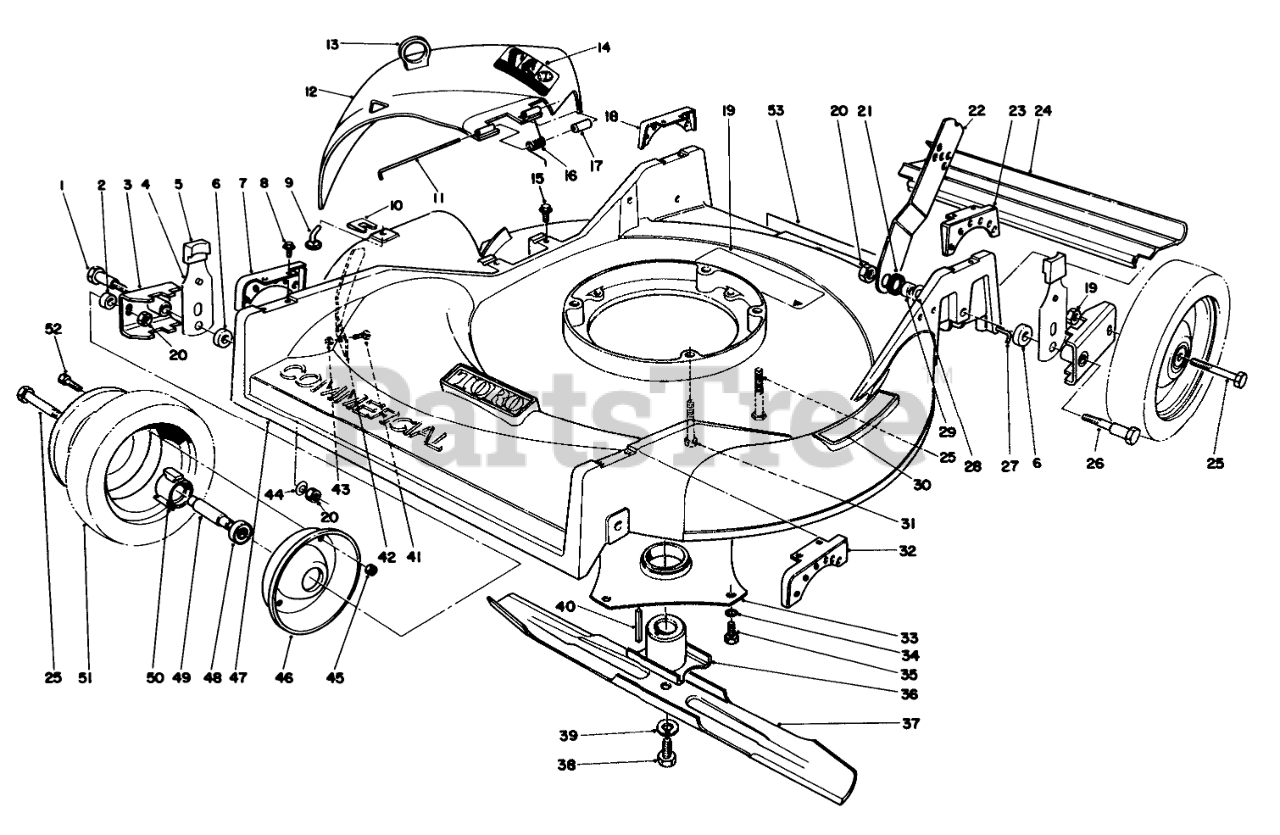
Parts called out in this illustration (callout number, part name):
1	PIVOT SCREW
2	SPACER-WHEEL
3	PIVOT ARM
4	SPRING ARM ASM-FRONT
5	KNOB-ARM
6	SPACER-PIVOT
7	FRT RIGHT QUAD
8	SCREW-HWHTF
9	BAG CHUTE PIN
10	BAG CHUTE CLIP PIN
11	DEFLECTOR HINGE PIN
12	Deflector (Incl. Ref. #14)
13	LIFT LOOP
14	Decal Danger
15	SCREW-HWH
16	DEFLECTOR SPRING
17	SLEEVE
18	REAR RIGHT QUAD
19	Decal-Danger
20	NUT-LOCK, NI
21	HANDLE LATCH SPACER
22	Latch-Handle
23	REAR LEFT QUAD
24	SHIELD - TRAILING
25	SCREW-HH
26	REAR PIVOT SCREW
27	SHIELD ROD
28	WASHER-BELLEVILLE
29	HANDLE LATCH SPACER
30	DECAL - STEP PAD INT'L
31	SCREW-HH
32	FRT LEFT QUAD
33	CRNKSHFT PROTECT ASM
34	WASHER-LOCK, INTERNAL
35	SCREW-HWHTF
36	RETAINER-BLADE
37	Blade
38	SCREW-HH
39	WASHER-LOCK
40	KEY-SQUARE
41	SCREW-CARR
42	Bar-Safety
43	NUT-LOCK, NI
44	WASHER-BELLEVILLE
45	NUT-LOCK, NI
46	Wheel-Half
47	Housing (Incl. Ref. #19 & 30)
48	BEARING-WHEEL
49	SPACER-BEARING
50	HUB-BEARING
52	SCREW-HHF
53	Decal
